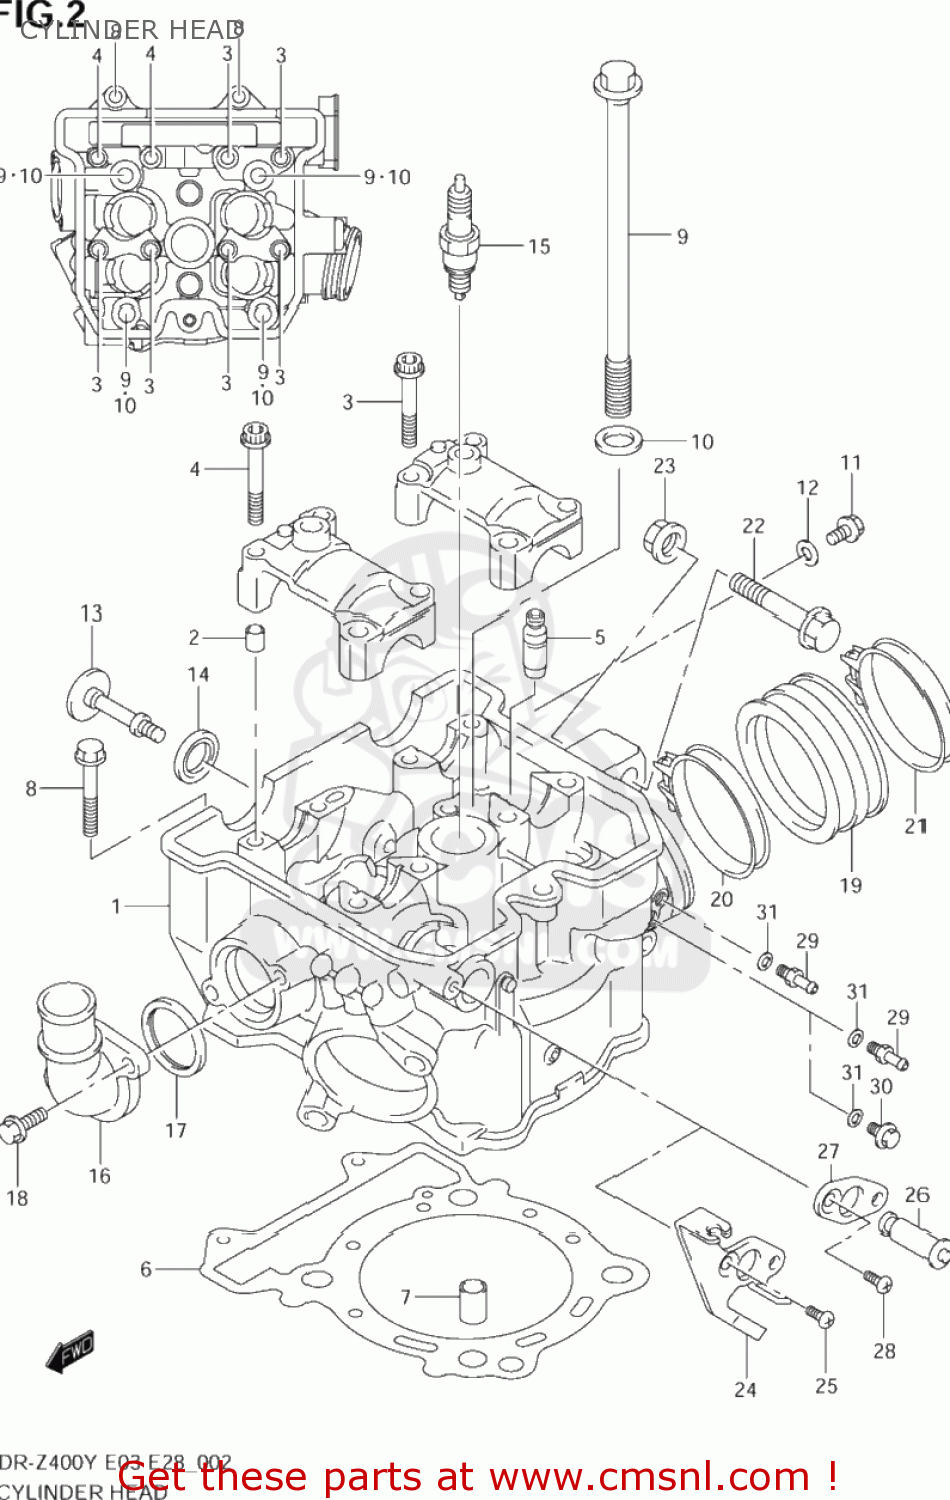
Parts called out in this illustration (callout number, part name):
1	HEAD ASSY,CYLINDER
2	PIN(6.2X8X11)
3	BOLT
5	GUIDE,VALVE
6	GASKET,CYLINDER HEAD (NAS)
7	PIN
8	BOLT(6X39)
9	BOLT(10X175)
10	WASHER(10.5X19X2)
11	BOLT
12	GASKET(5.8X13X1.2) (NAS)
13	BOLT,CYL HEAD SIDE FACE
14	WASHER,HEAD COVER
15	PLUG,SPARK(CR8E)
16	COVER,THERMOSTAT
17	SEAL,THERMOSTAT COVER
18	BOLT
19	PIPE,INTAKE
20	CLAMP
21	CLAMP
22	BOLT(10X50)
23	NUT
24	HOLDER,DECOMP CABLE
25	SCREW
26	PLUG,DECOMP SHAFT HOLE
27	RETAINER,DECOMP SHAFT SEAL
28	SCREW
29	UNION,INTAKE PORT
30	BOLT
31	GASKET(8.2X14X1) (NAS)
